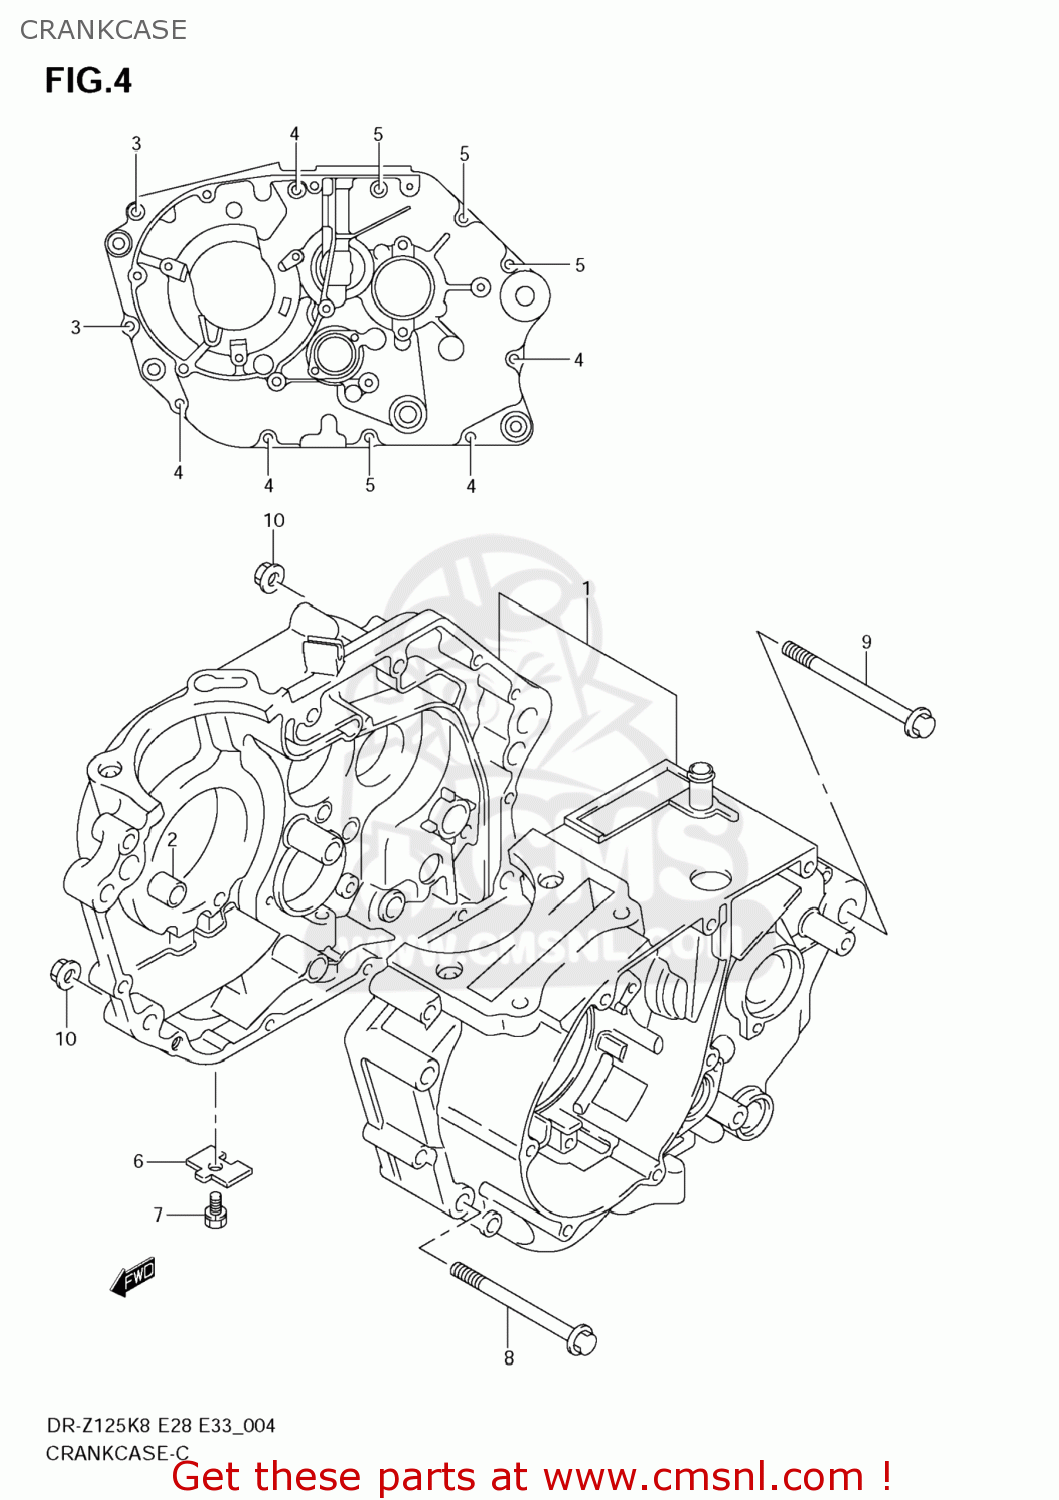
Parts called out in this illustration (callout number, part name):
1	CRANKCASE ASSY
2	PIN
3	BOLT
4	BOLT
5	BOLT
6	PLATE,OIL GALLERY PLUG
7	BOLT
8	BOLT(8X80)
9	BOLT(8X88)
10	NUT
